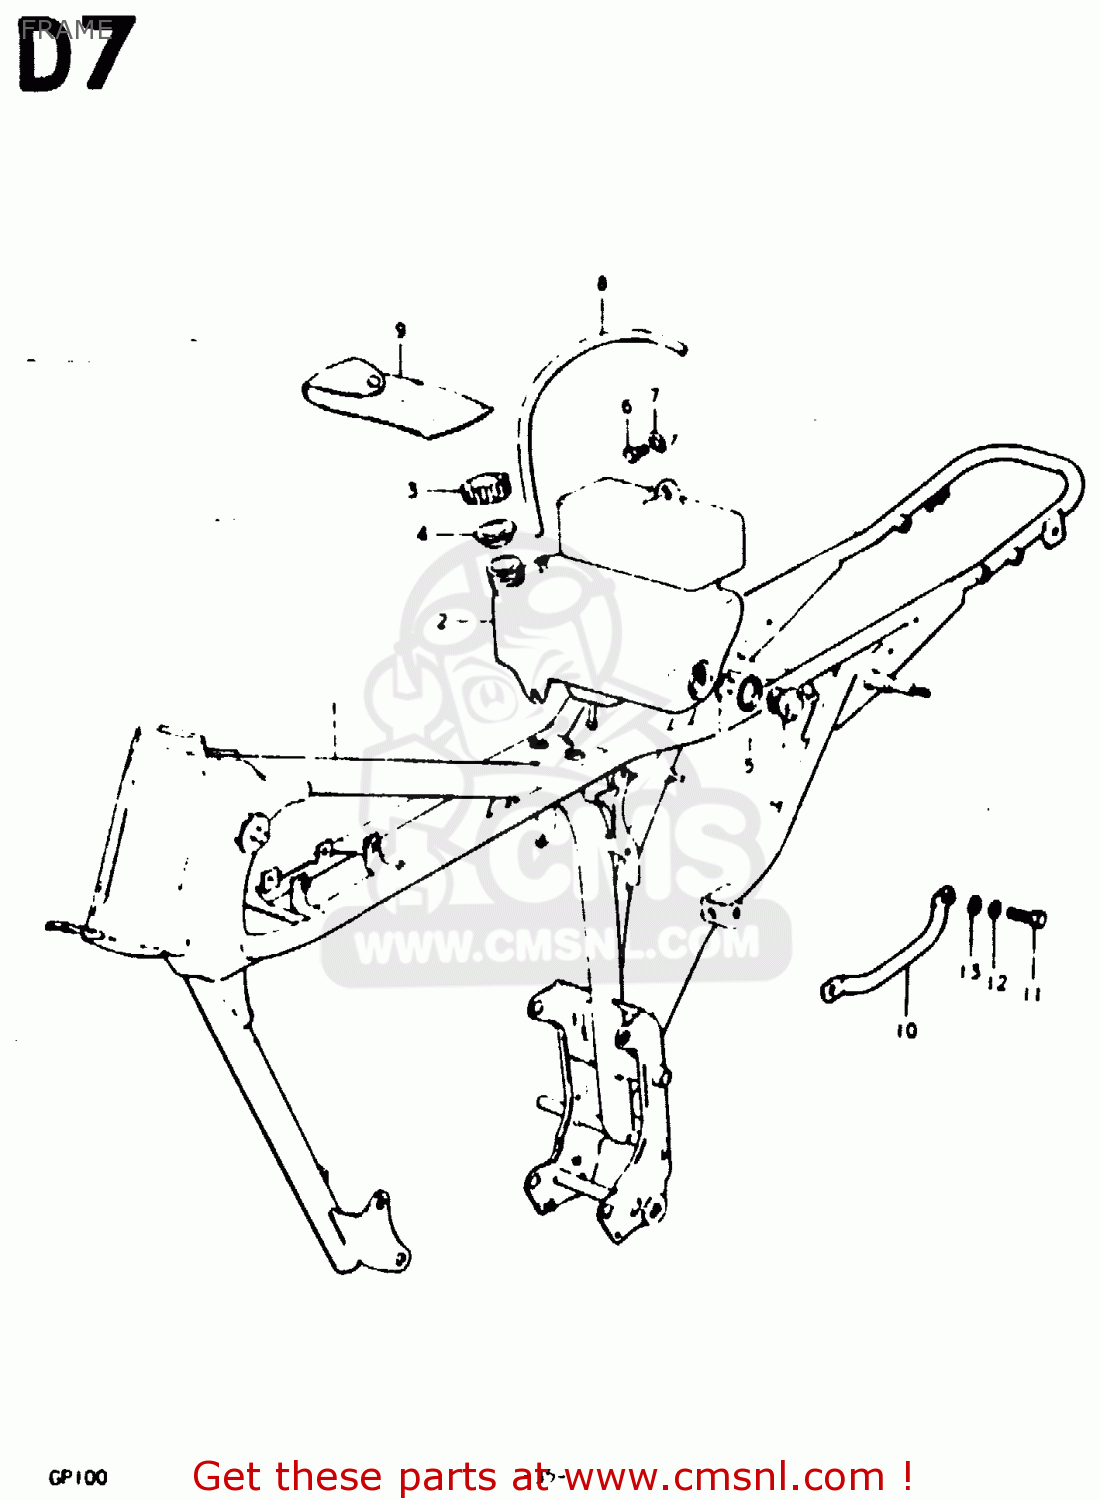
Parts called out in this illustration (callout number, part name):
1	FRAME
2	TANK,OIL
3	CAP,OIL TANK
4	GASKET,OIL TANK CAP (NAS)
5	LENS SET,OIL LEVEL
6	BOLT, UPPER
7	WASHER
8	HOSE
9	TOOL SET
